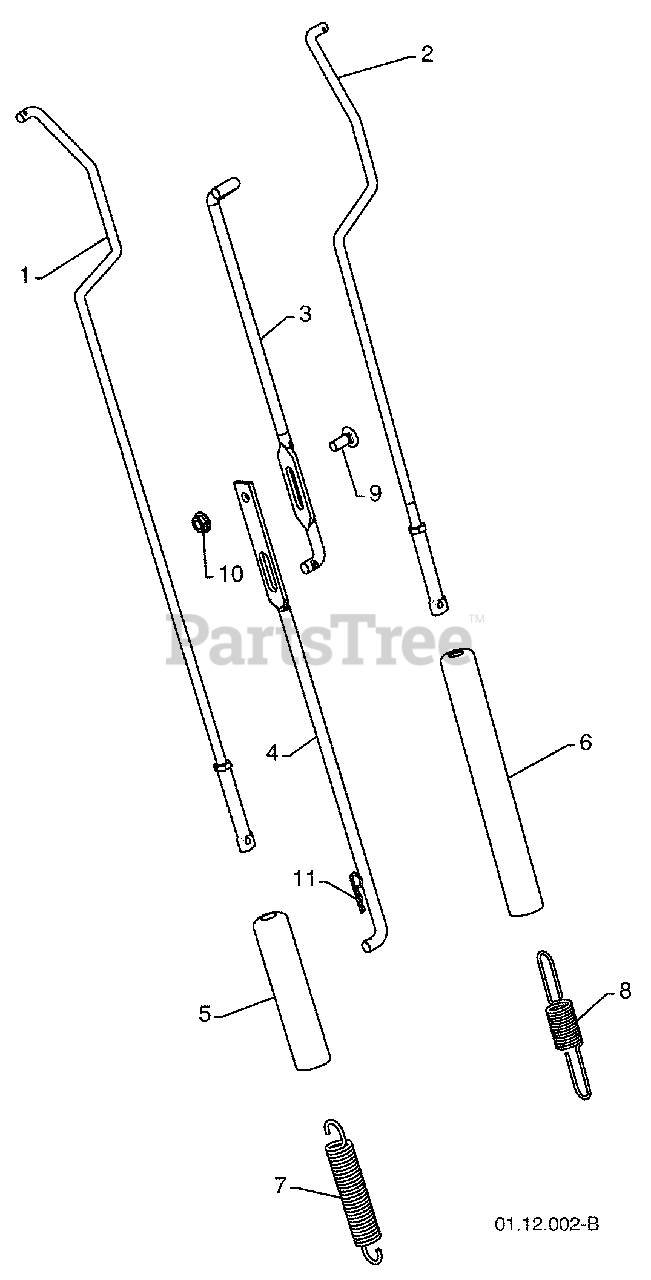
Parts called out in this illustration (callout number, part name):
1	IMPELLER ROD ASSEMBLY
2	TRACTION ROD ASSEMBLY
3	SHIFTER ROD TOP
4	SHIFTER ROD BOTTOM
5	SPRING SLEEVE
6	SPRING SLEEVE
7	IMPELLER SPRING
8	TRACTION SPRING
9	CARRIAGE BOLT 5/16-18 X .750
10	NUT 5/16-18
